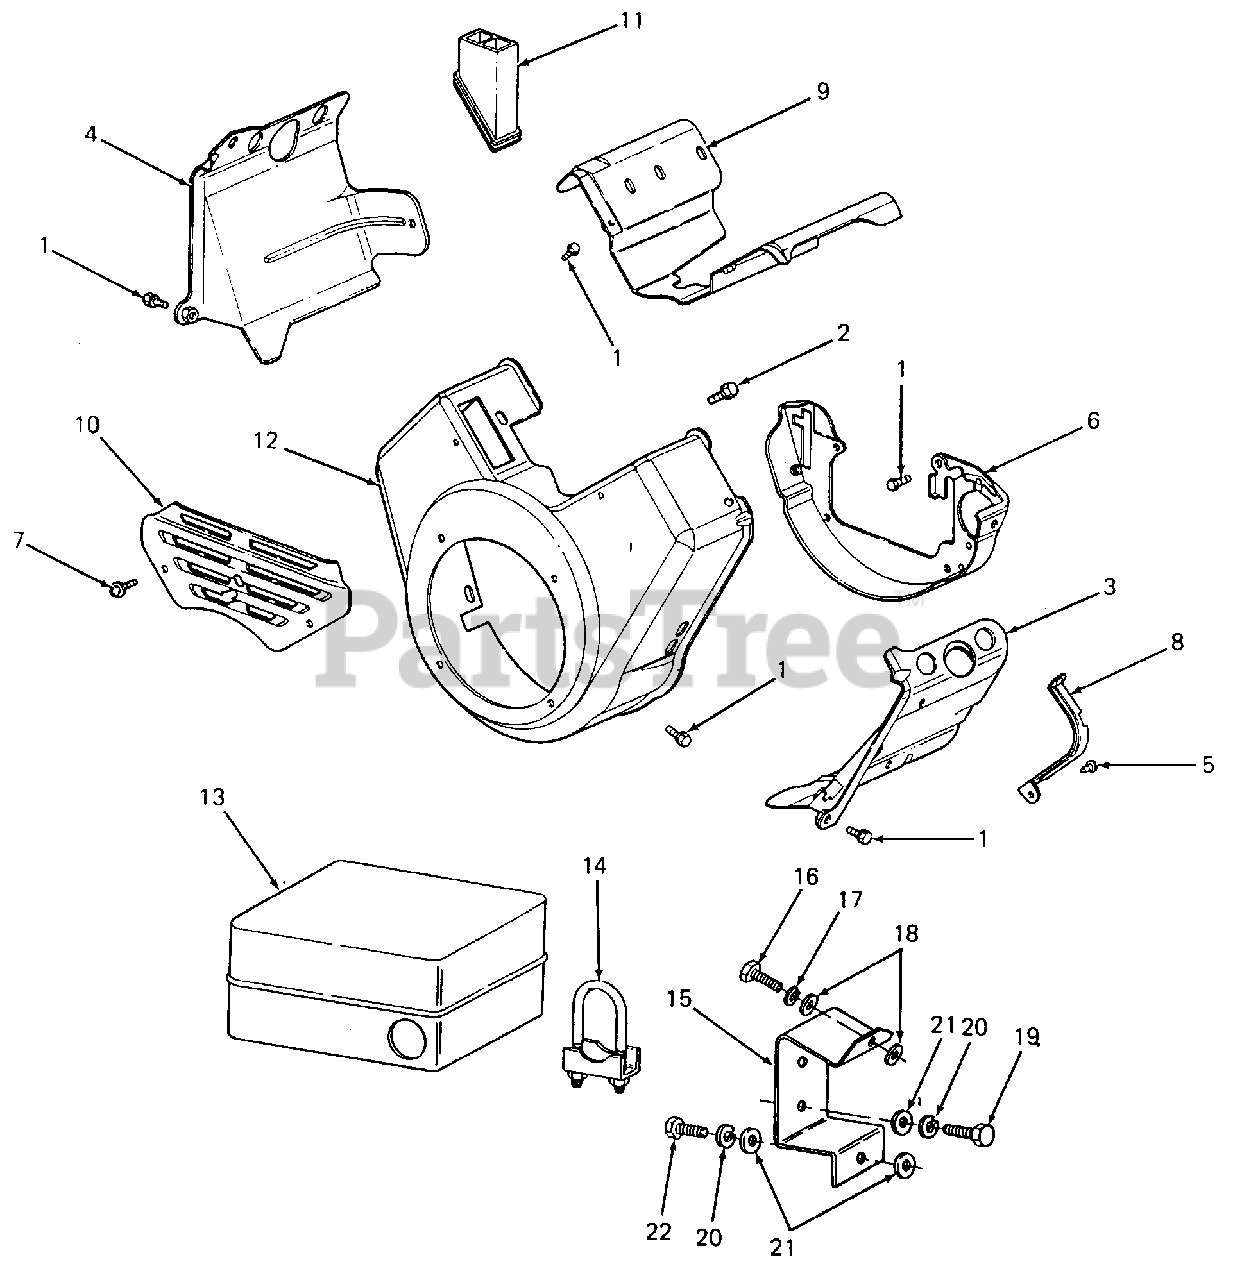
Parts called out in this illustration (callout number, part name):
1	Screw, Sems
2	Screw, Sems
3	Cover (Cyl #1)
4	Cover (Cyl #2)
5	Screw, Sems
6	Plate, Back
7	Screw, Sems
10	Cover, Carburetor
11	Tube, Air Inlet
12	Housing, Blower
13	Muffler
14	Clamp, Muffler
15	Bracket, Muffler
16	Screw, Hex Cap, M8 X 1.25 X 20 mm Lg
17	Washer, Lock, 5/16-.312
18	Washer, Flat, .344 X 1.125 X .063 Thk
19	Screw, Hex Cap, 1/4-20 X 1 Lg
20	Washer, Lock 1/4-.250
21	Washer, Flat, .281 X .734 X .063
22	Screw, Hex Cap, M6 X 1.0 X 16 mm Lg
